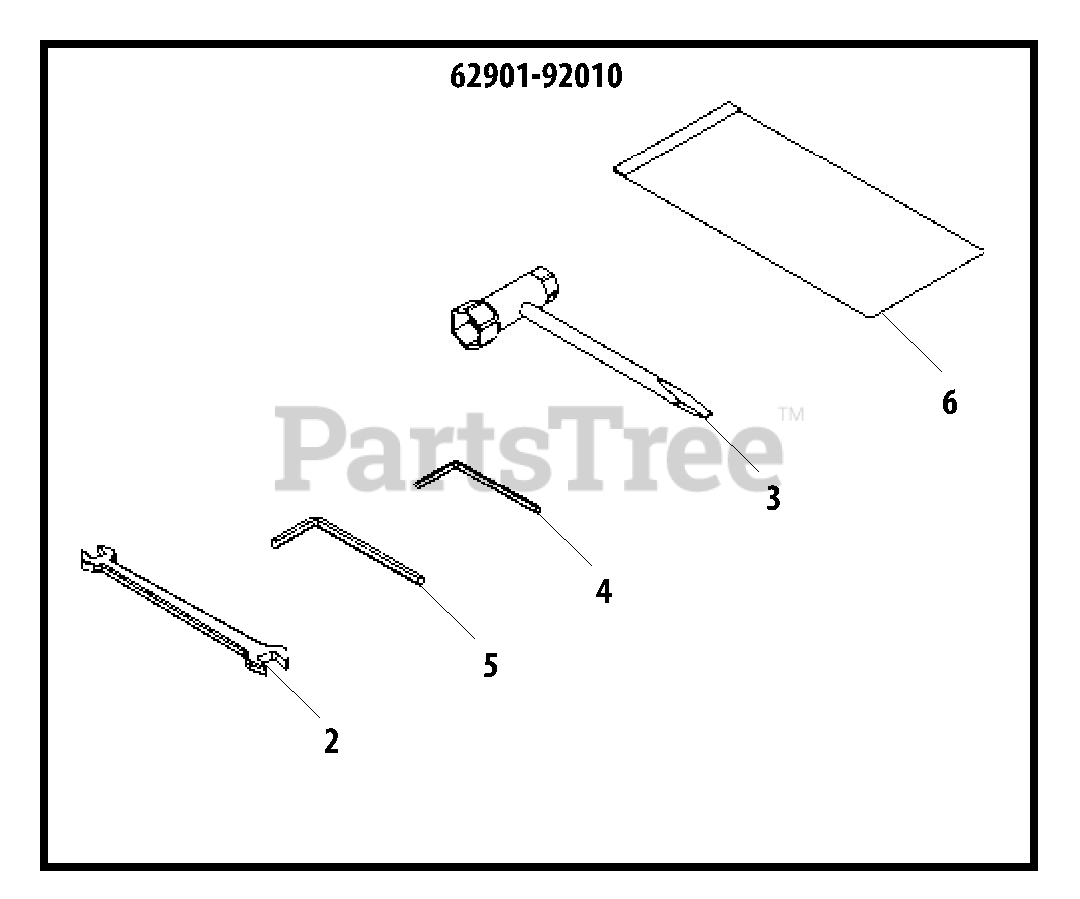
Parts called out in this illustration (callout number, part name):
2	SPANNER - 8X10mm
3	T-WRENCH - 13X16mm
4	HEX KEY - 3mm
5	HEX KEY - 4mm
6	BAG, TOOL
62901-92010	TOOL KIT
